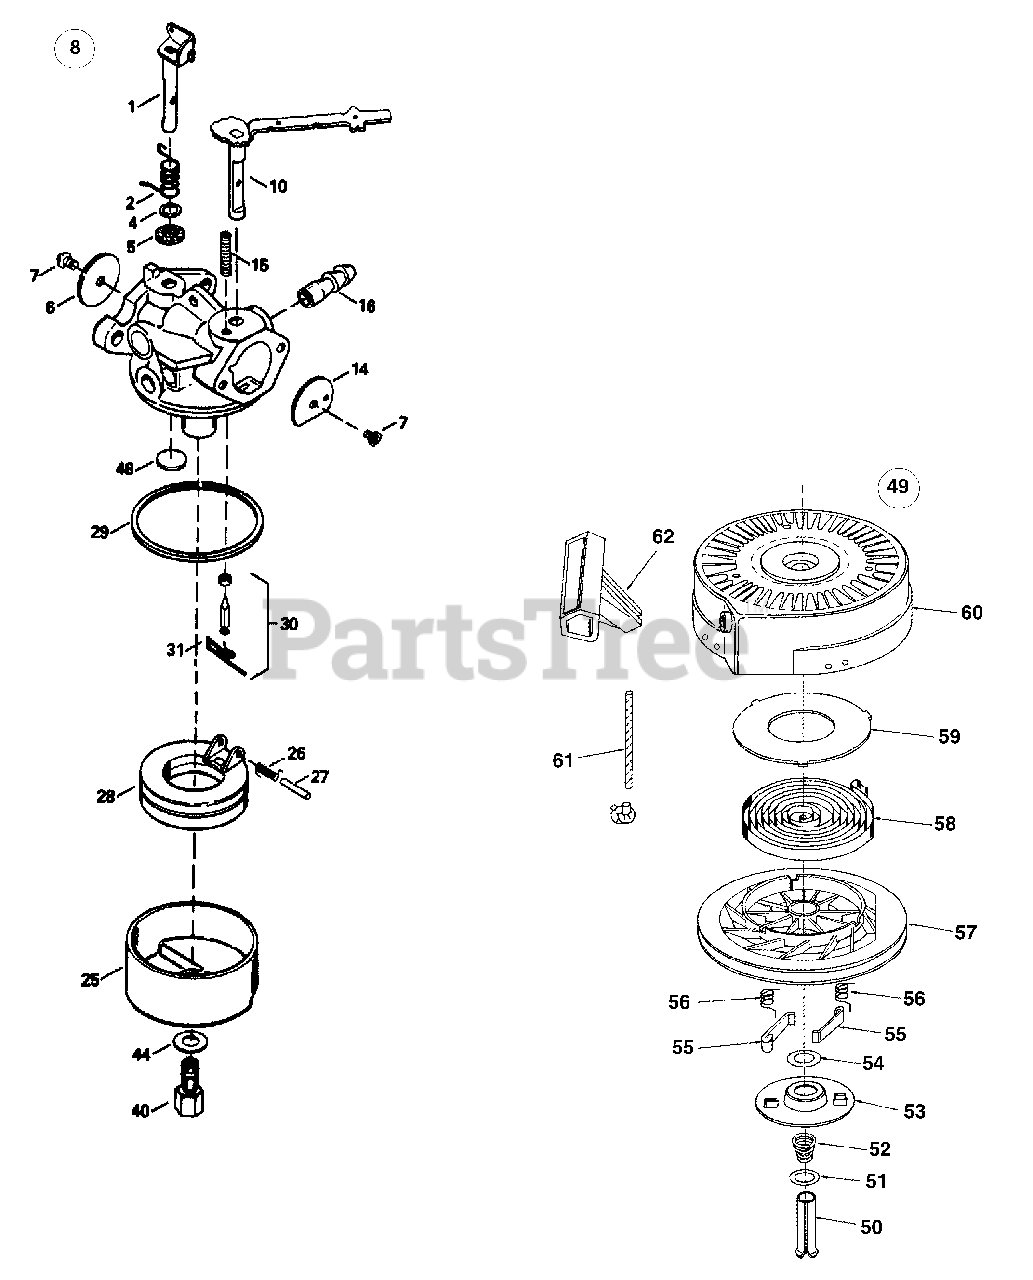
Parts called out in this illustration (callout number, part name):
1	Throttle Shaft & Lever Ass'y
2	Throttle Return Spring
4	Dust Seal Washer
6	Throttle Shutter
7	Throttle & Choke Shutter Screw
8	Carburetor Assembly
10	Choke Shaft & Lever Ass'y
15	Choke Positioning Spring
16	Fuel Fitting
25	Float Bowl
26	Float Dampening Screw
27	Float Shaft
28	Float
29	O-Ring, Float Bowl & Body
30	Inlet Needle, Seat & Clip
31	Spring Clip
40	High Speed Bowl Nut
44	Bowl Nut Washer
48	Welch Plug, Atmospheric Vent
49	Rewind Starter Ass'y
50	Spring Pin
52	Brake Spring
55	Starter Dog
56	Dog Spring
57	Pulley Ass'y
58	Rewind Spring
59	Spring Cover
60	Starter Housing Ass'y
61	Starter Rope (98")
62	Starter Handle
